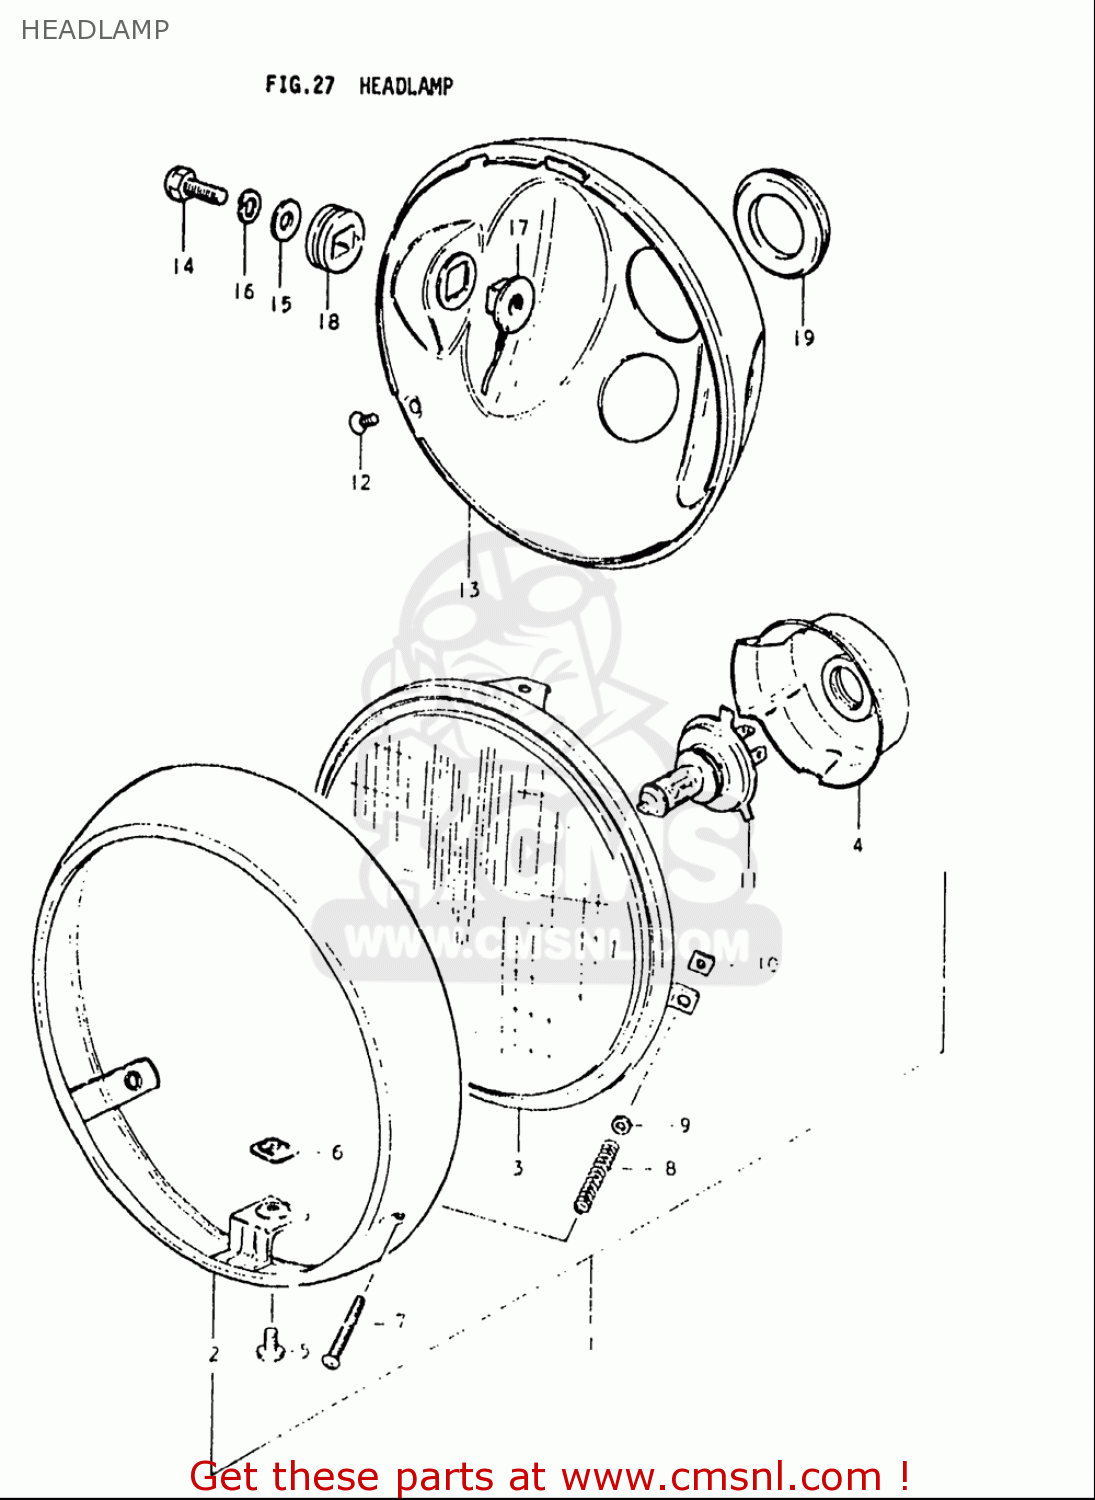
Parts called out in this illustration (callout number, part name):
2	RIM
5	SCREW
6	NUT
7	SCREW
8	SPRING
9	WASHER
10	NUT
11	BULB(12V60/55W,H4)
12	SCREW
13	HOUSING,HEADLAMP
14	BOLT
15	WASHER
16	WASHER,LOCK
17	SPACER,HEADLAMP HOUSING
18	CUSHION,HEADLAMP HOUSING
19	GROMMET,HEADLAMP HOUSING
